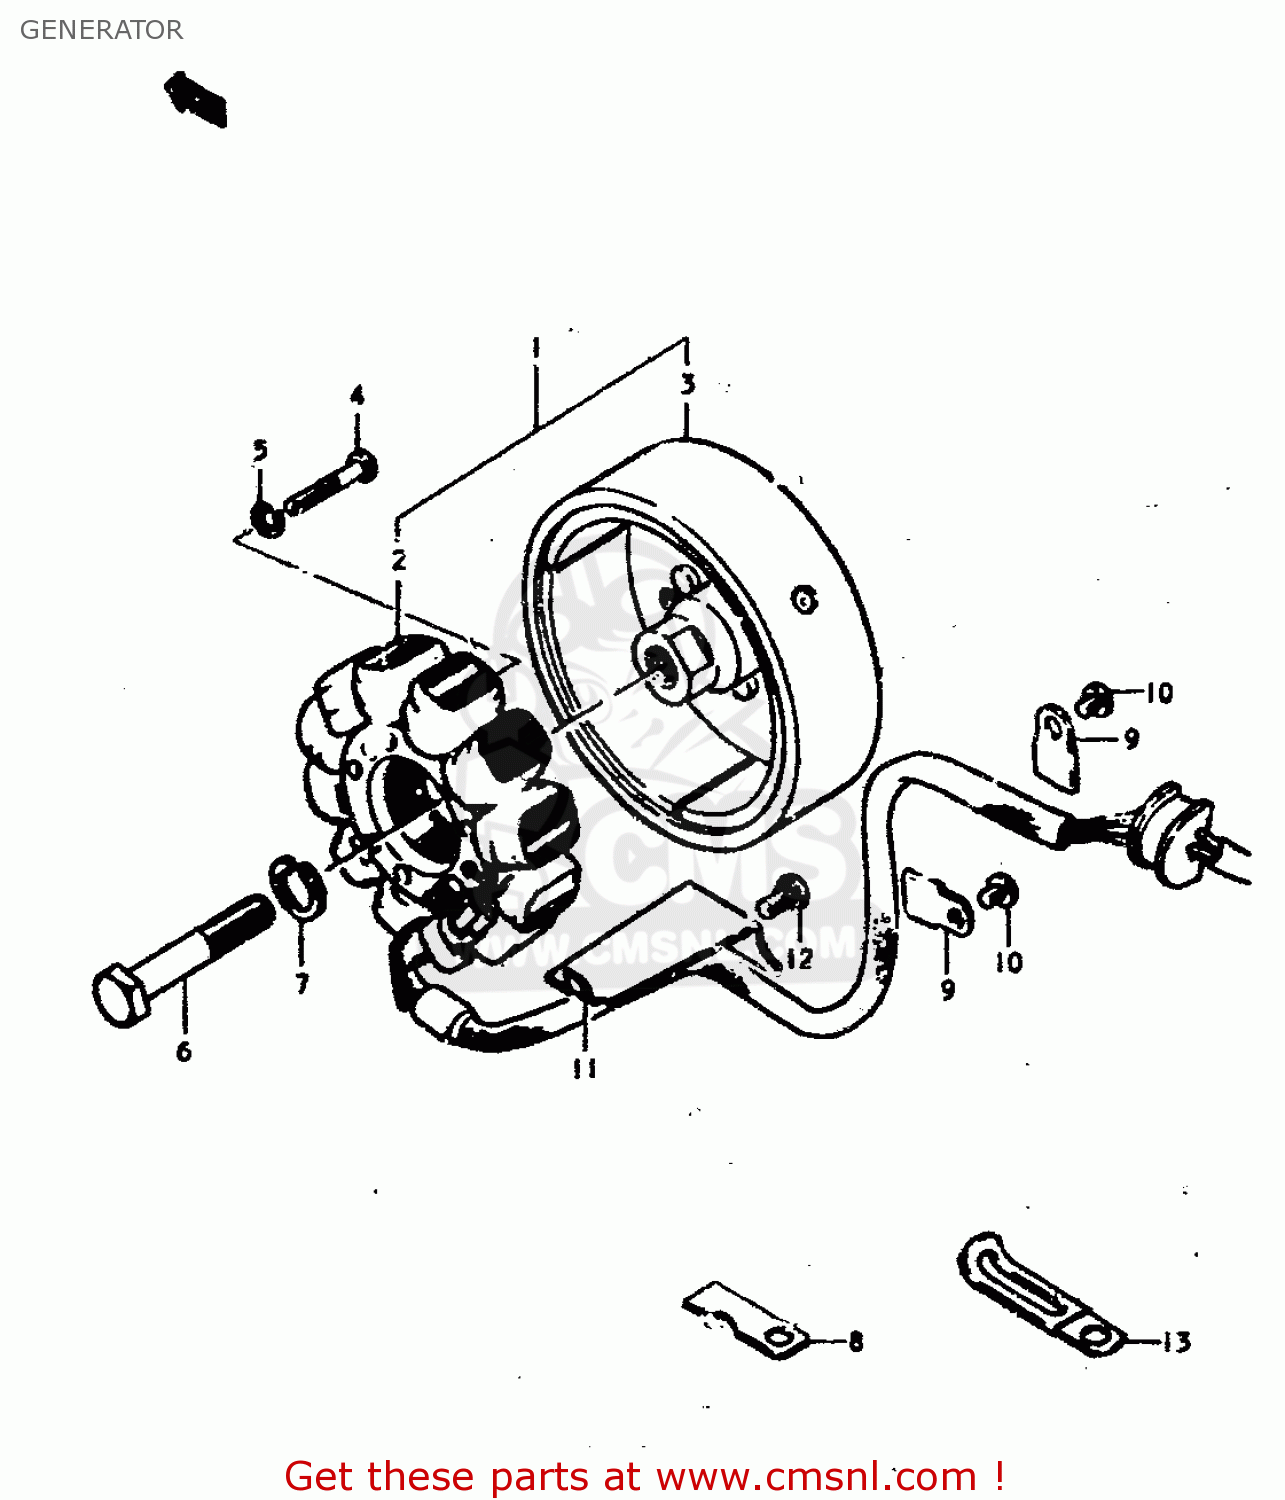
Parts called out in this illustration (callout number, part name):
1	GENERATOR ASSEMBLY
2	STARTER ASSY
3	ROTOR ASSEMBLY
4	SCREW
5	LOCK WASHER
6	BOLT 12X45
7	WASHER,LOCK 12
8	CLAMP,GENERATOR LEAD WIRE
9	CLAMP,GENERATOR LEAD WIRE
10	SCREW
11	CLAMP,GENERATOR LEAD WIRE
12	SCREW
13	CLAMP L:35
